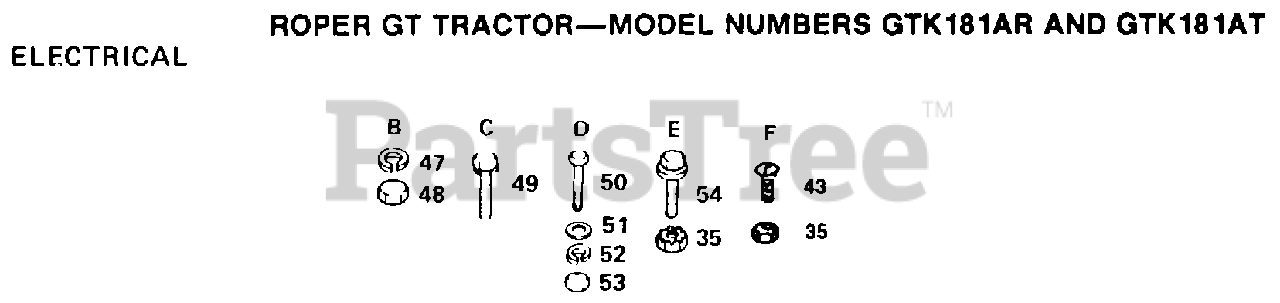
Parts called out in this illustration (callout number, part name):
35	"NUT,KEPS"
48	NUT
49	SCREW ST
50	BOLT LT
51	WASHER
52	LOCKWASHER
54	SCREW
